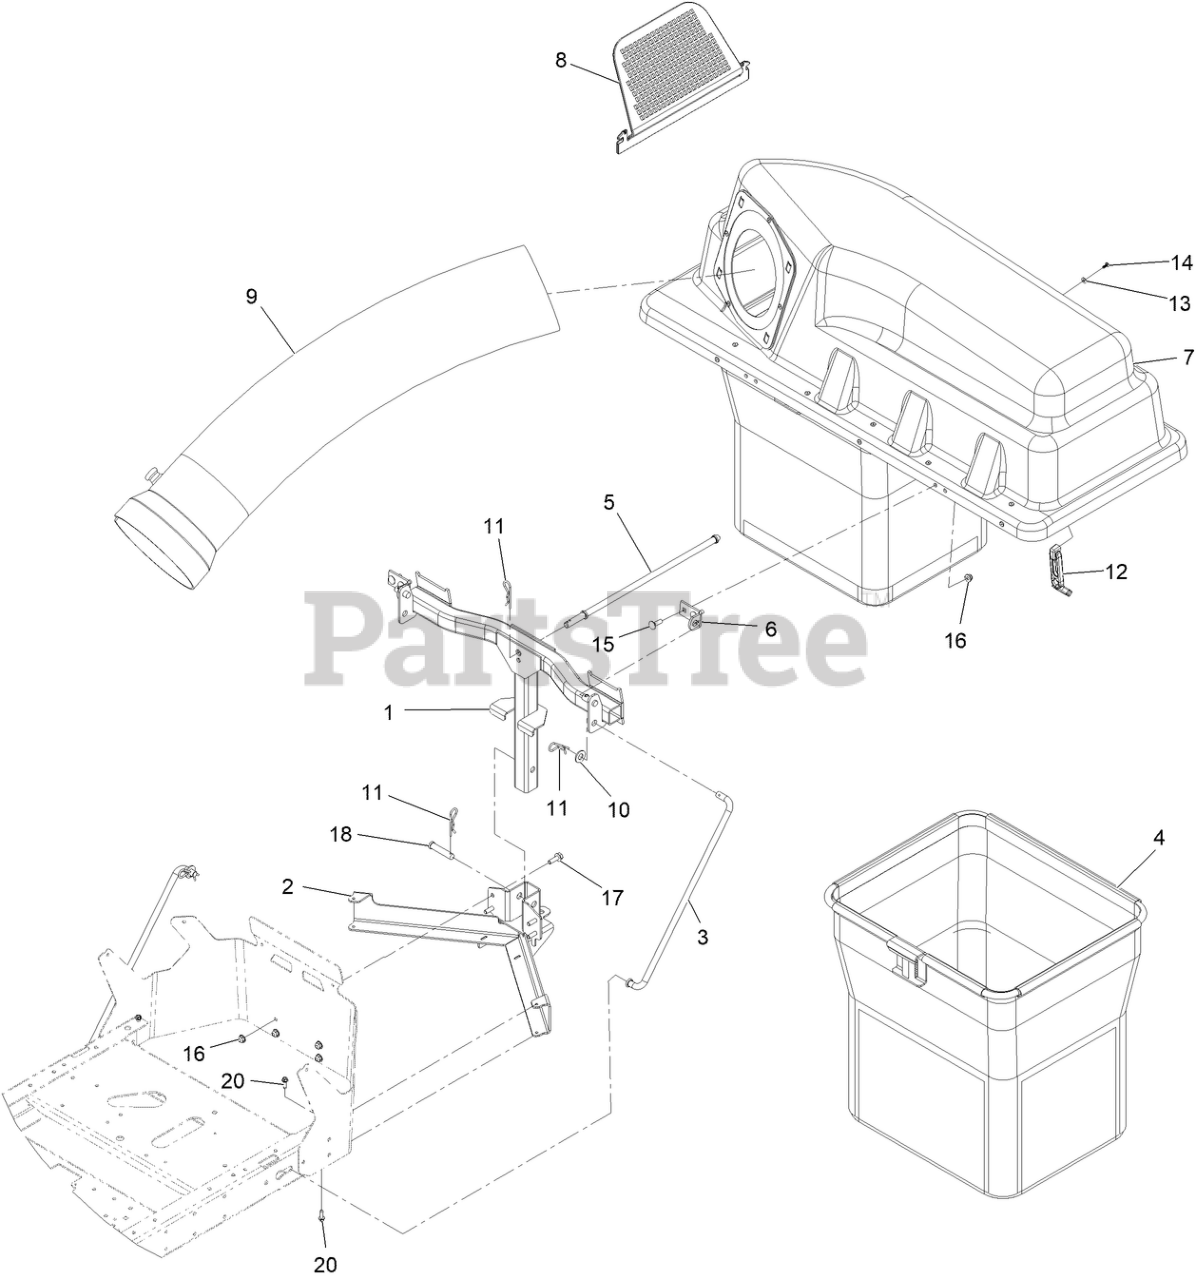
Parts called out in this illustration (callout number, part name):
1	FRAME ASM PIVOT
2	MOUNT-LOWER, BAGGER
3	ROD-SUPPORT, CZ
4	BAG ASM
5	ROD-HOOD, DOWN (HOLD)
6	BRACKET-HOPPER PIVOT
7	Top ASM-Bagger
8	SCREEN-BAGGER
9	TUBE-BAGGER
10	WASHER-FLAT
11	PIN-HAIR
12	LATCH-RUBBER
13	Washer-Plain
14	SCREW-PLASTIC, PTH
15	Bolt-CARR
17	SCREW-HHF
18	PIN-CLEVIS
20	SCREW-HWHTF
